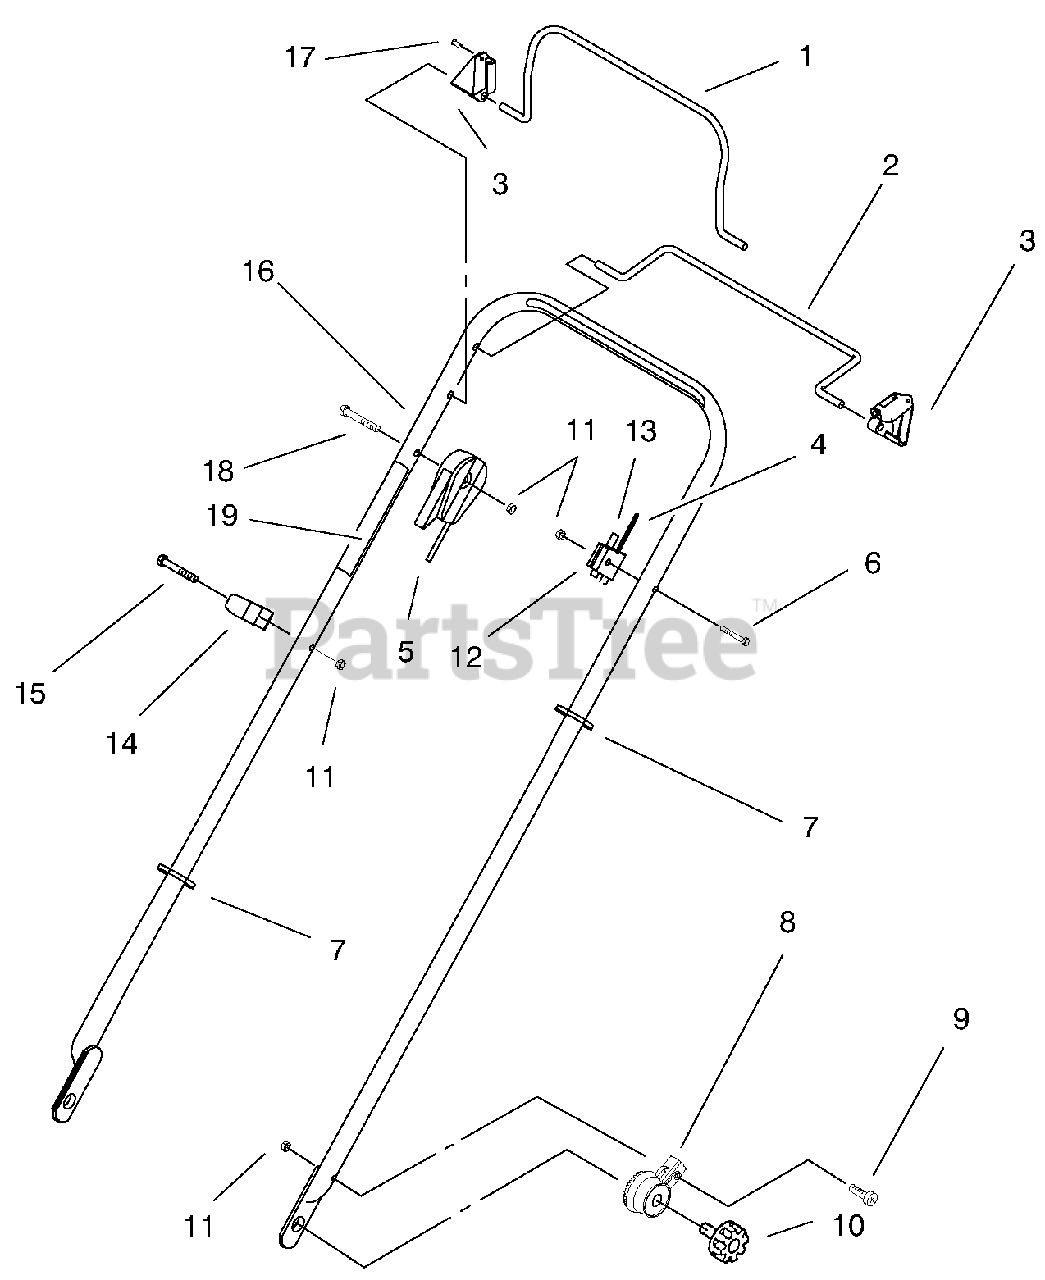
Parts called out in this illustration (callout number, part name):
1	Bail-Brake Int'l
2	Bail-SP Control Int'l
3	Stop-Pivot
4	Cable-Brake
5	Cable-Throttle
6	Screw-Hex Hd. Cap
7	Tie-Cable
8	Handle-Knuckle
9	Screw-Pan Hd.
10	Knob-Handle Mount
11	Nut-Lock
12	Support-Cable
13	Cable-Traction
14	Guide-Rope
15	Screw-Hex Hd. Cap
16	Handle-Int'l
17	Rivet-Pop
18	Screw-Hex Hd. Cap
19	Decal-Operation
